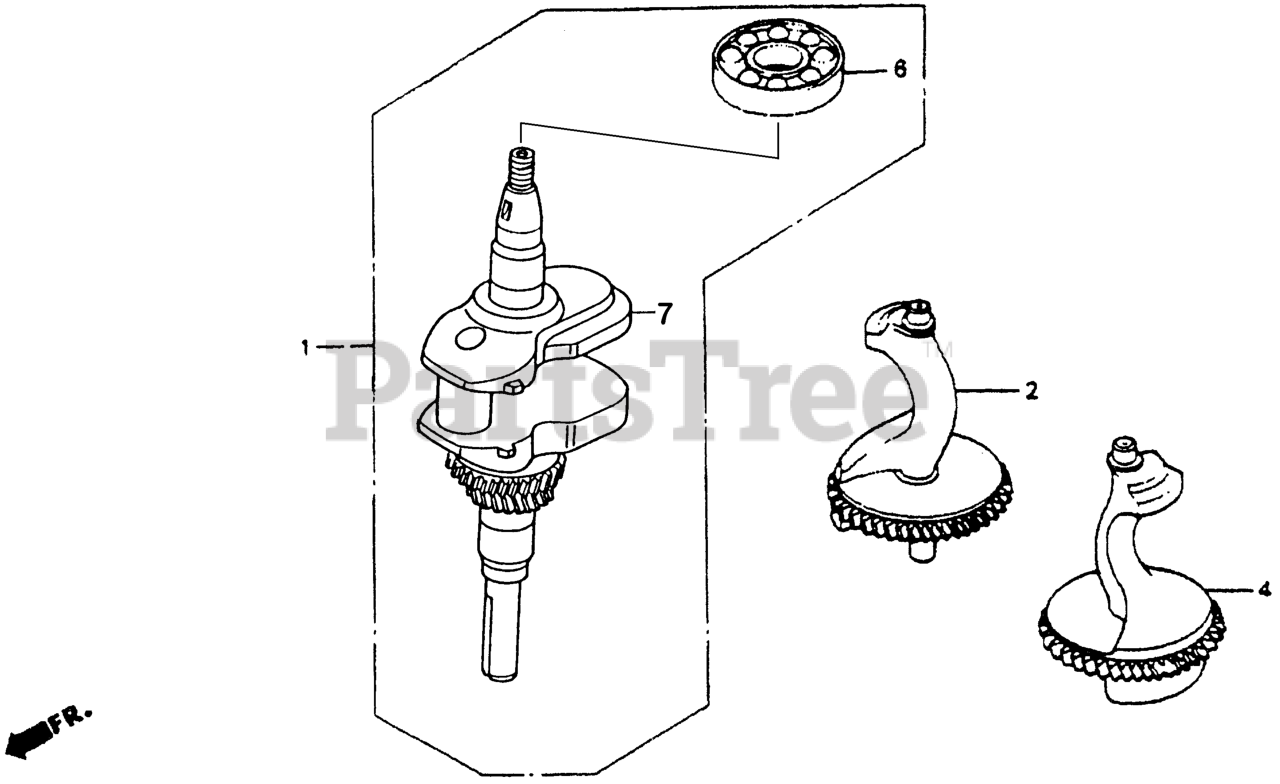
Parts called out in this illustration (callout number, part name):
1	CRANKSHAFT
2	WEIGHT A, BALANCER
4	WEIGHT B, BALANCER
6	BEARING, RADIAL BALL (6207)
7	CRANKSHAFT
